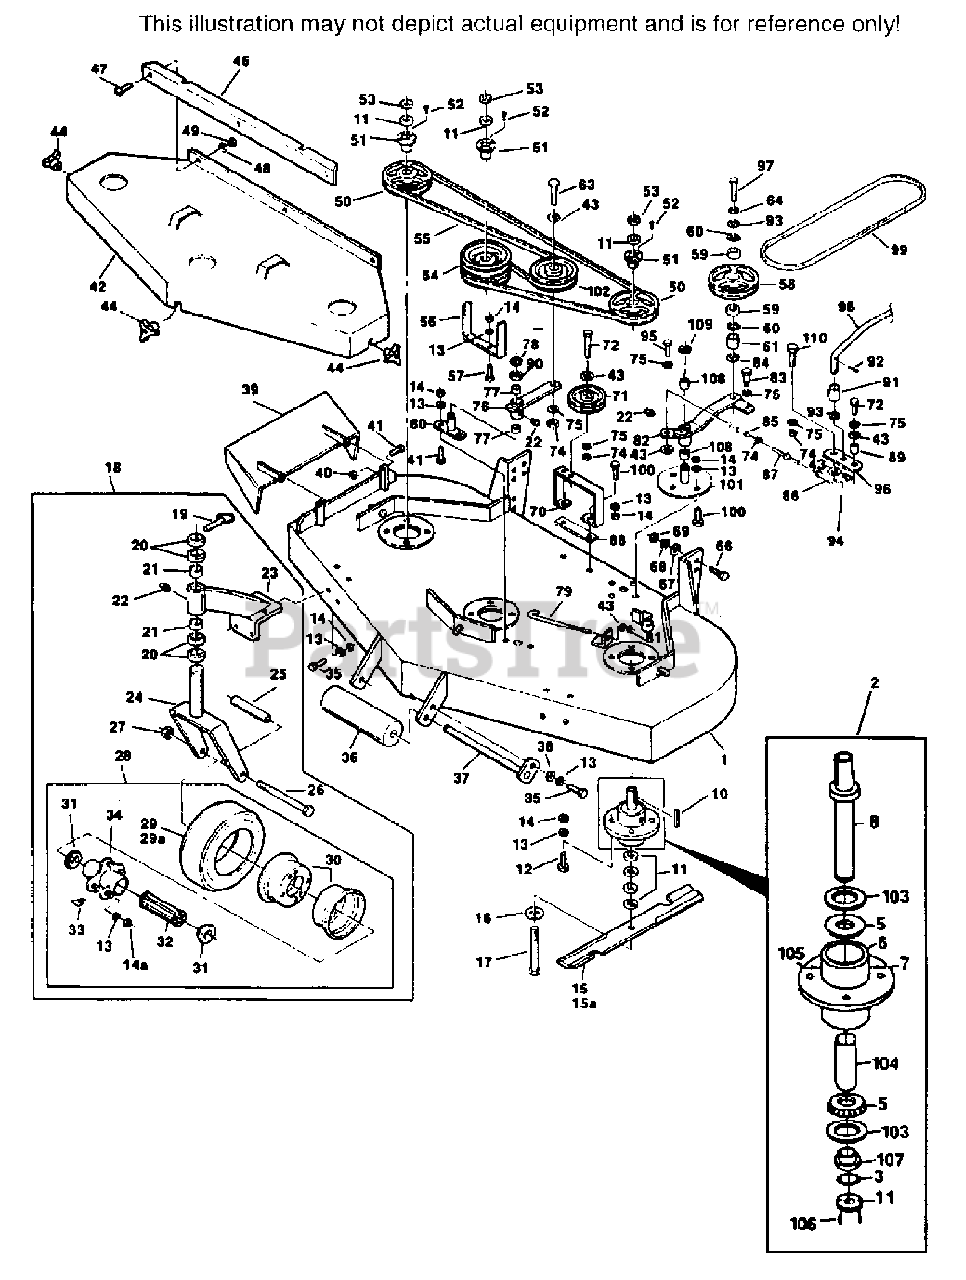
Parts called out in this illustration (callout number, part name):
1	CUTTER DECK(INCL. DECAL)
2	SPINDLE ASSEMBLY, TAPERED BEARING
3	RETAINING RING, 1" EXT.-INVERTED
5	TAPERED BEARING
6	SPINDLE HOUSING, TAPERED BEARING
7	GREASE FITTING, STR. 5/16 SERRATED
8	SPINDLE SHAFT, TAPERED BEARING
10	KEY, 1/4 X 1/4 X 2"
11	SPACER, CUTTER BLADE
15	CUTTER BLADE, 21" STANDARD LIFT
15A	CUTTER BLADE, 21" HIGH LIFT
16	FLAT WASHER, 5/8W
17	BOLT, HEX HD., 5/8-11 X 9-1/2"
18	CASTER ASSY, COMP.(INCL. 19-28)
19	QUICK PIN
20	SPACER, CASTER YOKE, 1/2" LONG
21	BRONZE BEARING
22	GREASE FITTING, STR, 1/4-28
23	SUPPORT ASSY.(INCL. 21-22)
24	CASTER YOKE
25	SLEEVE, CASTER WHEEL BEARING
26	BOLT, HEX HD., 1/2-13 X 5-1/2"
28	WHEEL ASSY.(INCL. 13-14, 14A, 29-34)
29	TIRE ONLY, CASTER WHEEL
29A	INNER TUBE ONLY, CASTER WHEEL
30	RIM PAIR, CASTER WHEEL
31	RETAINER, BEARING, CASTER WHEEL
32	ROLLER BEARING, CASTER WHEEL
33	GREASE FITTING, 45' 1/4-28
34	HUB ASSY. W/BOLTS
36	GUIDE ROLLER
37	ROLLER SHAFT
38	WASHER, 3/8 X 7/8 X 13 GA.
39	DISCHARGE CHUTE
40	HEX NUT, 5/16-18 ELASTIC STOP
42	BELT COVER(INCL. DECALS)
43	WASHER, 25/64 X 15/16 X 12 GA.
44	WING NUT, 3/8-16
46	BELT COVER SKIRT
47	MACHINE SCREW, 1/4-20 X 1/2 TRUSS HEAD
50	PULLEY(INCL. 51-52)
51	TAPER HUB
54	PULLEY, DOUBLE(INCLUDES 51-52)
55	BELT, BLADE DRIVE
56	BELT GUIDE
58	PULLEY IDLER
59	BEARING
60	RETAINING RING, 1-9/16" INT. BASIC
70	IDLER PULLEY SUPPORT
71	PULLEY, BELT GUIDE
77	BRONZE BEARING
78	RETAINING RING, 3/4" EXT.-"E"
79	ROD, IDLER PULL, J
81	HEX NUT, 3/8-16 ELASTIC STOP
82	IDLER ARM ASSY.(INCL. 22 & 77)
83	SHOULDER BOLT
86	ROD END, RH(SILVER COLORED)
87	LINK, TURNBUCKLE
88	SPACER BAR
89	SLEEVE, CAM CLUTCH
90	WASHER 3/4(49/64 X 1-1/4 X 16 GA.)
91	SLEEVE, CLUTCH ROD
93	WASHER, 33/64 X 1 X 16 GA.
94	HAIR PIN, LARGE
96	CAM LINK
99	BELT, CUTTER DRIVE
101	IDLER PIVOT
102	PULLEY, IDLER
103	SEAL, TAPERED BEARING SPINDLE
104	SLEEVE, TAPERED BEARING SPINDLE
105	RELIEF FITTING, TAPERED BEARING SPINDLE
107	BUSHING, TAPERED BEARING SPINDLE
108	BRONZE BEARING
109	RETAINING RING - EST. "E" - 1-1/8"
